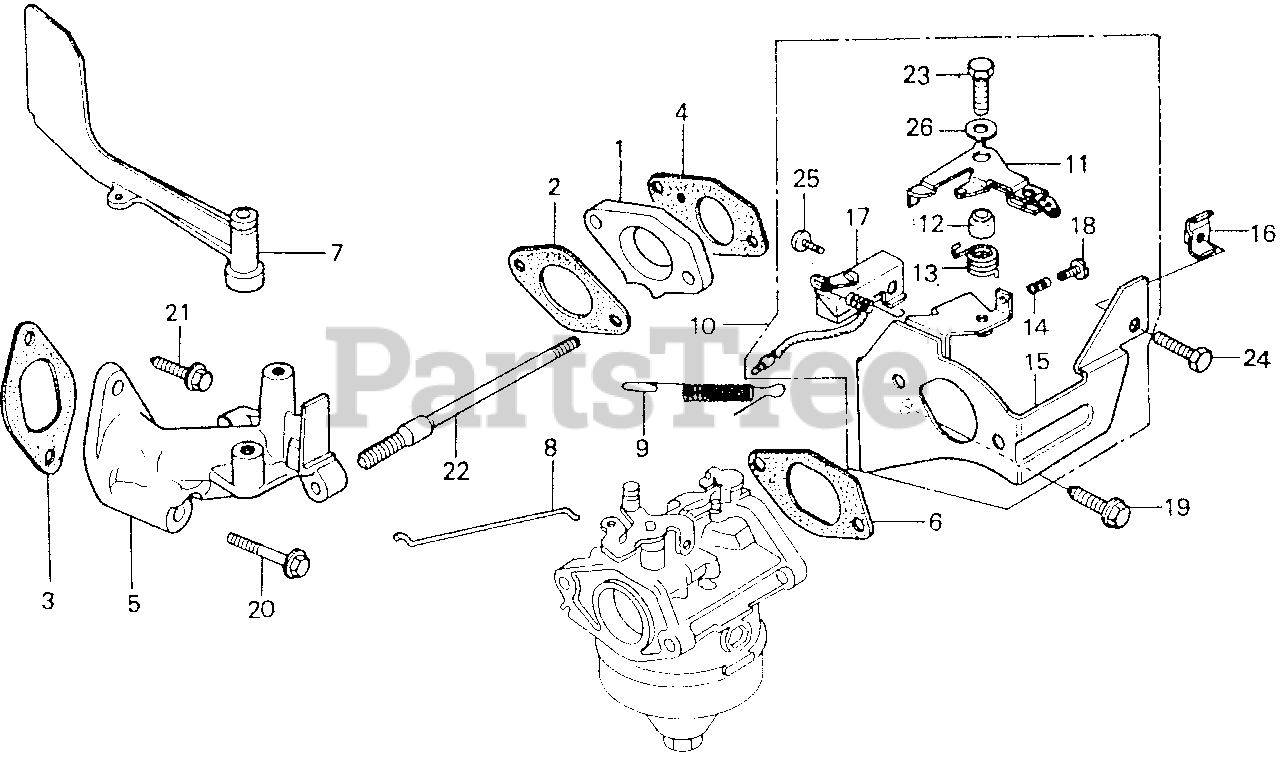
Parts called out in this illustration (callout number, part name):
1	INSULATOR, CARBURETOR
2	GASKET, INSULATOR
3	GASKET, MANIFOLD (Honda Code 0671933). (NOT AVAILABLE)
4	GASKET, CARBURETOR
5	MANIFOLD, IN.
6	GASKET, AIR CLEANER
7	FLUTTER, GOVERNOR
8	ROD, GOVERNOR (Honda Code 0671990). (NOT AVAILABLE)
9	SPRING, GOVERNOR
10	CONTROL ASSY.
11	LEVER, CONTROL
12	COLLAR, LEVER SETTING
13	SPRING, RETURN
14	SPRING, STOPPER LEVER
15	STAY, CLEANER CASE
16	HOLDER, WIRE
17	SWITCH ASSY., ENGINE STOP
18	BOLT (4X20) (NOT AVAILABLE)
19	BOLT, FLANGE (6X12) (CT200)
20	BOLT, FLANGE (6X50)
21	BOLT, FLANGE (6X20) (CT200)
22	BOLT, STUD (6X141)
23	BOLT, HEX. (5X20)
24	BOLT, HEX. (6X14)
25	SCREW, PAN (4X8)
26	WASHER, PLAIN (5MM)
